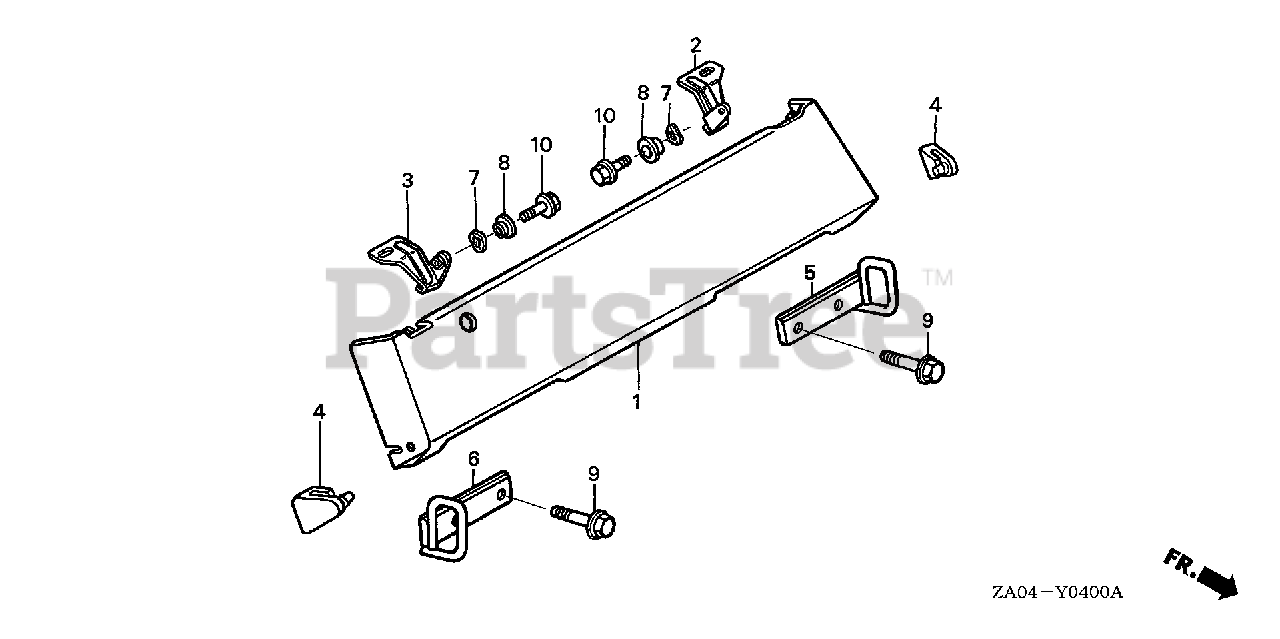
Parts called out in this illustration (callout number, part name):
1	LID, TOP
2	BRACKET, R. TOP LID
3	BRACKET, L. TOP LID
4	STOPPER, TOP LID
5	HOOK, R. FR.
6	HOOK, L. FR.
7	WASHER, WAVE
8	WASHER B
9	BOLT, FLANGE (8X14)
9	BOLT, FLANGE (8X16)
10	BOLT, FLANGE (6X12)
